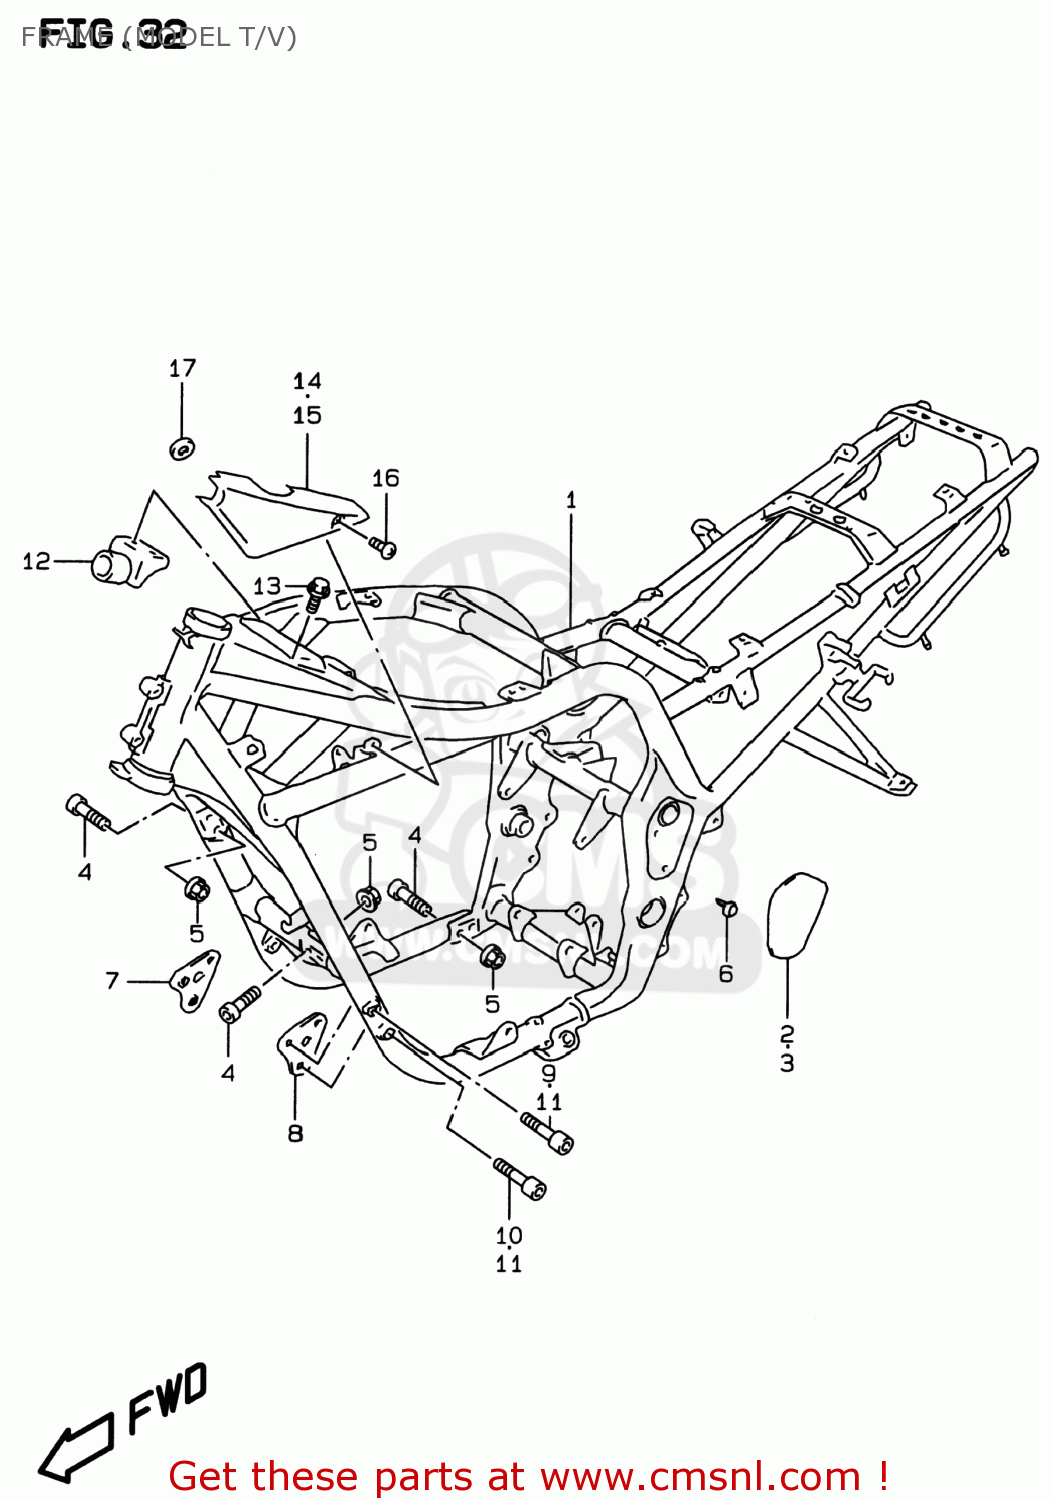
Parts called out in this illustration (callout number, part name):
1	FRAME COMP
2	COVER,FRAME BODY,R
3	COVER,FRAME BODY,L
4	BOLT(10X33)
5	NUT
6	CLIP
7	PLATE,ENG MTG,R
8	PLATE COMP,ENGINE MOUNTING
9	BOLT
10	BOLT
11	BOLT
12	DAMPER,FRAME
13	BOLT
14	COVER,FRAME HEAD,R
15	COVER,FRAME HEAD,L
16	SCREW(5X12)
17	CUSHION
